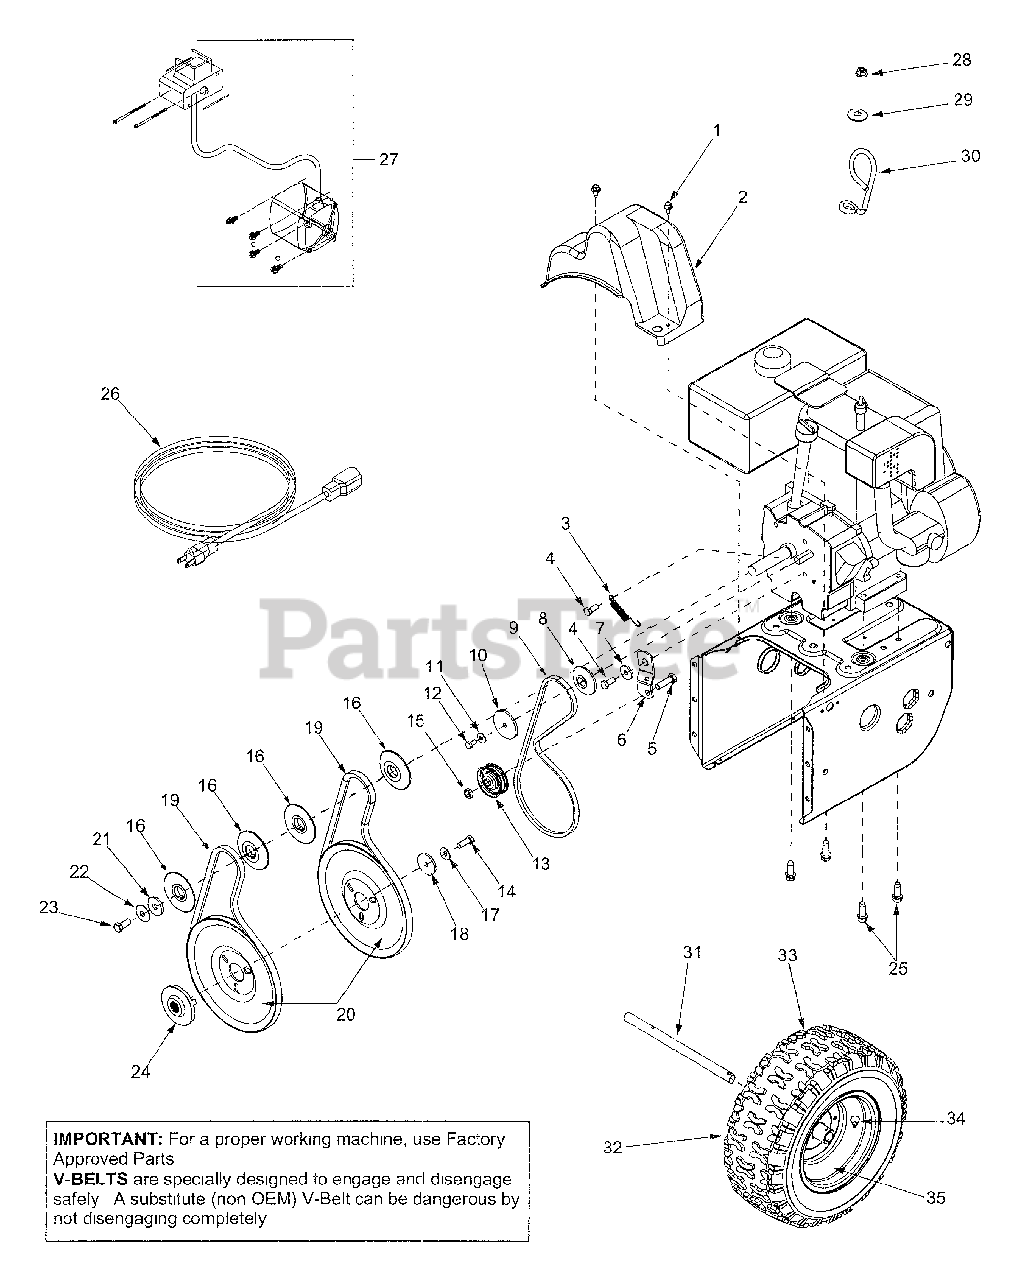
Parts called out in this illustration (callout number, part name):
1	Hex Washer Screw 1/4-20 x .625
2	Belt Cover
3	Extension Spring
4	Hex Screw 5/16-24 x .75
5	Hex Cap Screw 3/8-16 x 1.25
8	Pulley Half
9	V-Belt
10	Pulley Half
11	Bell Washer
12	Hex Cap Screw 1/4-28 x .50
13	Flat Idler
14	Lock Hex Cap Screw 5/16-24
15	Lock, Jam Nut 3/8-16
16	Pulley Half
17	Bell Washer
18	Flat Washer
19	Belt
20	Auger Pulley
21	Flat Washer 3/8 x 1.25 OD
22	Bell Washer
23	Hex Cap Screw 3/8-24
24	Adapter Pulley
25	Hex Screw 3/8-16 x 1.0
26	Extension Cord
27	Electric Start Kit
28	Lock Nut, 1/4-20
29	Flat Washer, .28 x .74 x .063
30	Cable Guide
31	Axle: .75 dia. x 12.2" Lg.
33	Tire 16.0" x 6.5" x 8"
34	Tubeless Air Valve
